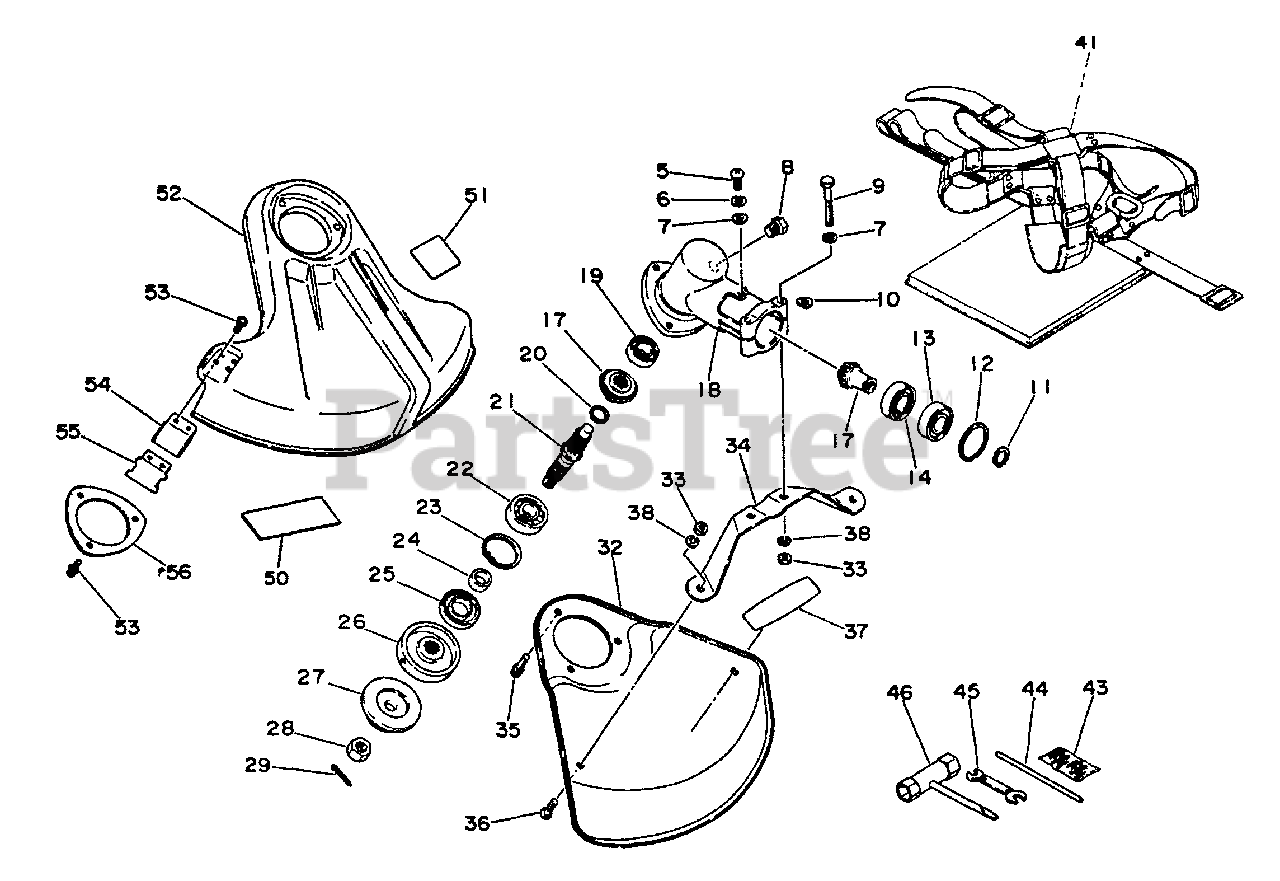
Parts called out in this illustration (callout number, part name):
5	SCREW 5×10
6	GEAR CASE ASSY
7	WASHER, FLAT 5.5×10×0.8
8	BOLT 8×8 SP
9	BOLT 5×40
11	RING, RETAINING - 12
12	RING, SNAP 28
13	BEARING, BALL 6001
14	BEARING, BALL 6001
17	GEAR SET
18	CASE, GEAR
19	BEARING, BALL 6000
20	RING, RETAINING - 12
21	SHAFT, GEAR
22	BEARING, BALL - 6201 C3
23	RING, SNAP Ø32
24	SPACER 11.8×15×9
25	SEAL, OIL 22
26	PLATE, ADAPTER - UPPER
27	PLATE, ADAPTOR - LOWER
29	PIN, COTTER 2×22
32	SHIELD
33	NUT M5
34	BRACKET, SHIELD
35	SCREW 5×10
36	SCREW 5×8
37	LABEL - ECHO
38	WASHER, SPRING 5
41	SHOULDER STRAP ASSY
43	PIN, COTTER 2×22 (PKG. OF 10)
44	TOOL, LOCKING 5×120 MM
45	SPANNER 8×10
46	T-WRENCH
50	LABEL, ECHO
51	LABEL - CAUTION
52	SHIELD ASSY
53	KNIFE, TRIMMER LINE
54	PROTECTOR
55	SCREW 5×16
56	PLATE, SHIELD Ø49.5 MM
